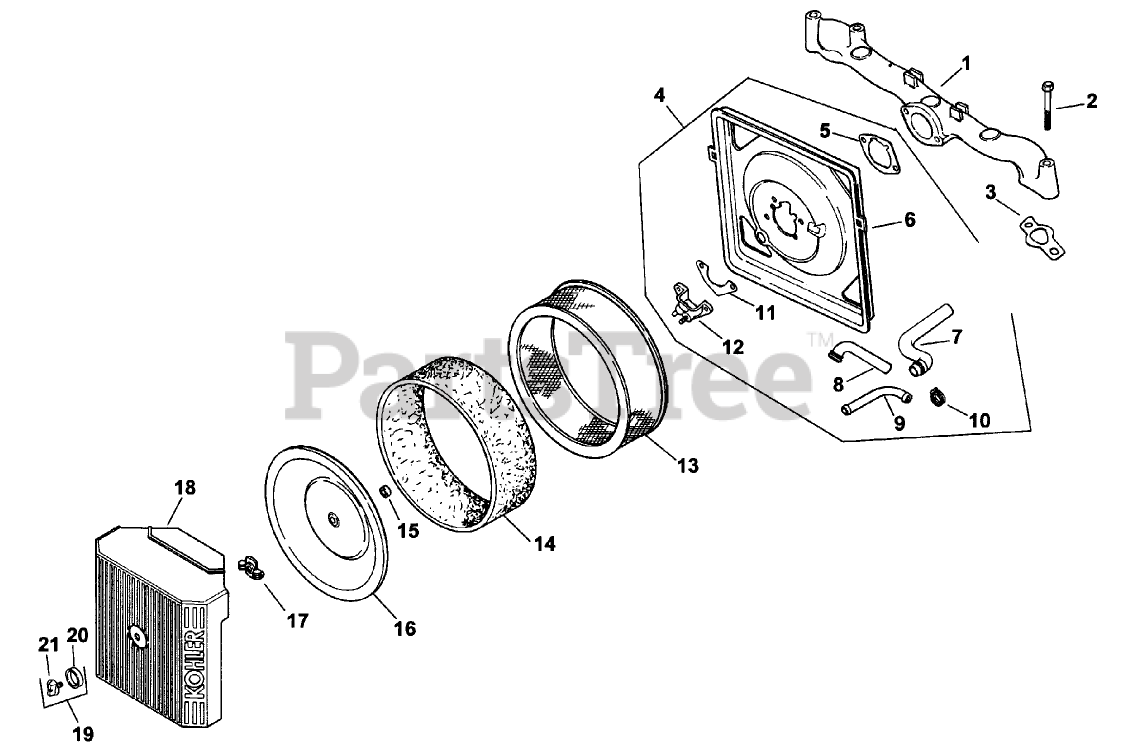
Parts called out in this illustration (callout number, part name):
1	Manifold-Intake
2	Screw
3	Gasket-Intake, Manifold
4	Kit, air cleaner base (Includes 5-12)
5	Gasket-A/C Base
6	Base, air cleaner
7	Hose-Breather
8	Hose-Breather
9	Fitting
10	Clamp
11	Gasket-Fuel Spitback
12	Cup, fuel spitback
13	Bement-Air Cleaner
14	Bement-Precleaner
15	Seal, insert
16	Cover-Inner AirCleaner
17	Wingnut
18	Cover-Air Cleaner
19	Kit, knob with seal (Includes 20,21)
20	O-Ring
21	Knob-Cover
